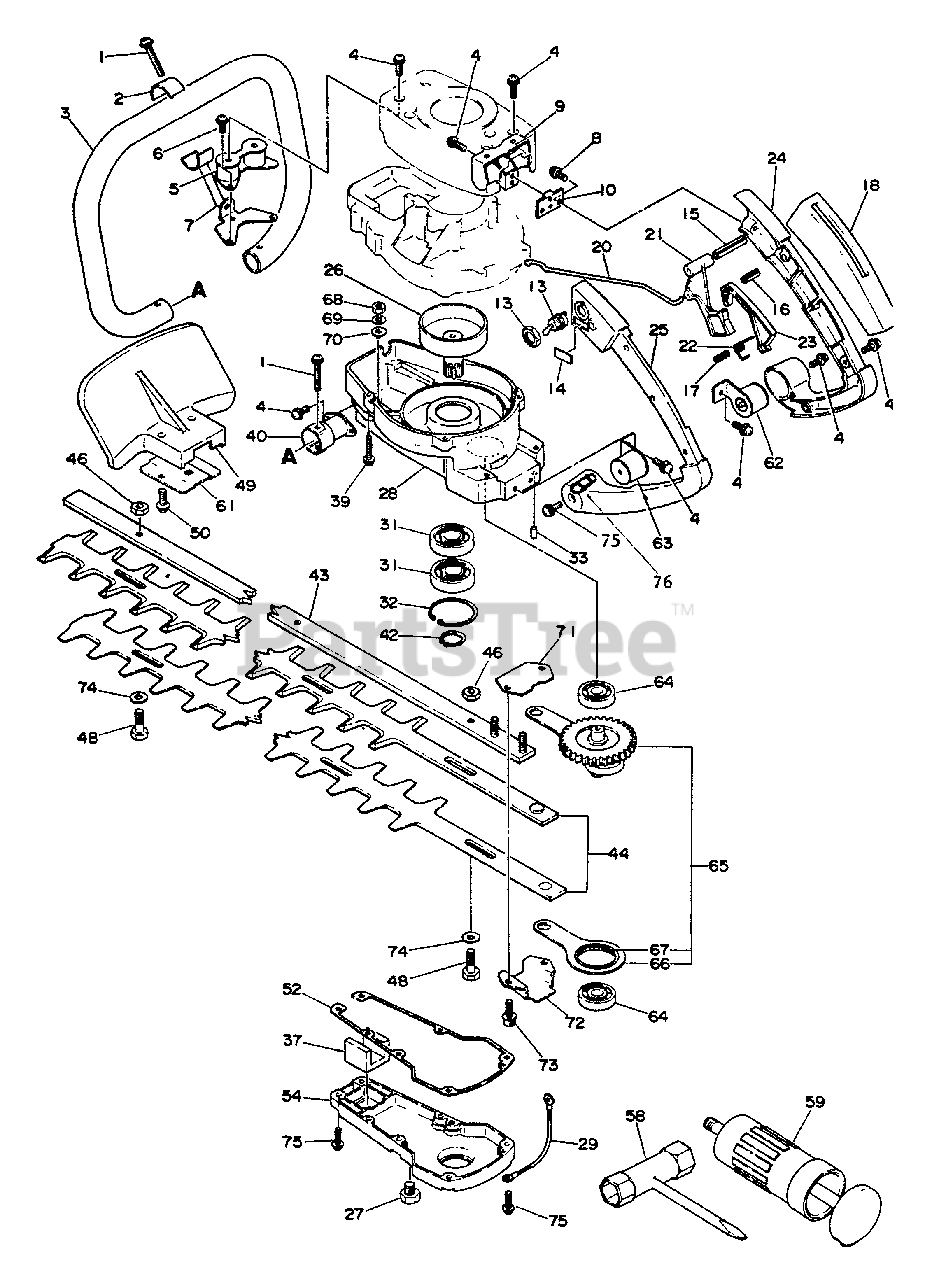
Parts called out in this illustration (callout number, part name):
1	SCREW 4×30
3	HANDLE, FRONT
4	SCREW 4×12
6	SCREW 4×8
8	SCREW 4×10
10	PLATE
13	SWITCH, ON-OFF
14	LABEL, ON-OFF
15	PIN, SPRING 5×32
16	PIN, SPRING 4×16
17	PIN, SPRING 3×14
20	ROD, THROTTLE
21	TRIGGER, THROTTLE
22	SPRING, TORSION
23	LOCKOUT, THROTTLE
24	HANDLE - REAR
25	HANDLE - REAR
26	DRUM, CLUTCH
27	BOLT 8×8 SP
28	CASE, GEAR
29	LEAD - GROUND
31	BEARING, BALL 6003
32	RING, SNAP 35
33	PIN, LOCATING 4
37	SEAL, FELT
39	SCREW 4×22
40	CUSHION
42	RING, RETAINING - 16
43	BAR, FRAME
44	TRIMMER BLADE SET
46	LOCKNUT - 6
48	BOLT 6×22
49	GUARD
50	SCREW 5×12
52	GASKET, GEAR CASE
54	LID, GEAR CASE
58	T-WRENCH
59	PUMP, GREASE
62	CUSHION
63	CUSHION
64	BEARING, BALL 6200
65	GEAR ASSY
66	CONNECTING ROD ASSY
67	BEARING, NEEDLE
68	NUT M5
69	WASHER, SPRING 6
70	WASHER 6.5×11.5×0.8
71	GUIDE
72	GUIDE
73	BOLT 5×14
75	SCREW 4×14
76	SPACER
